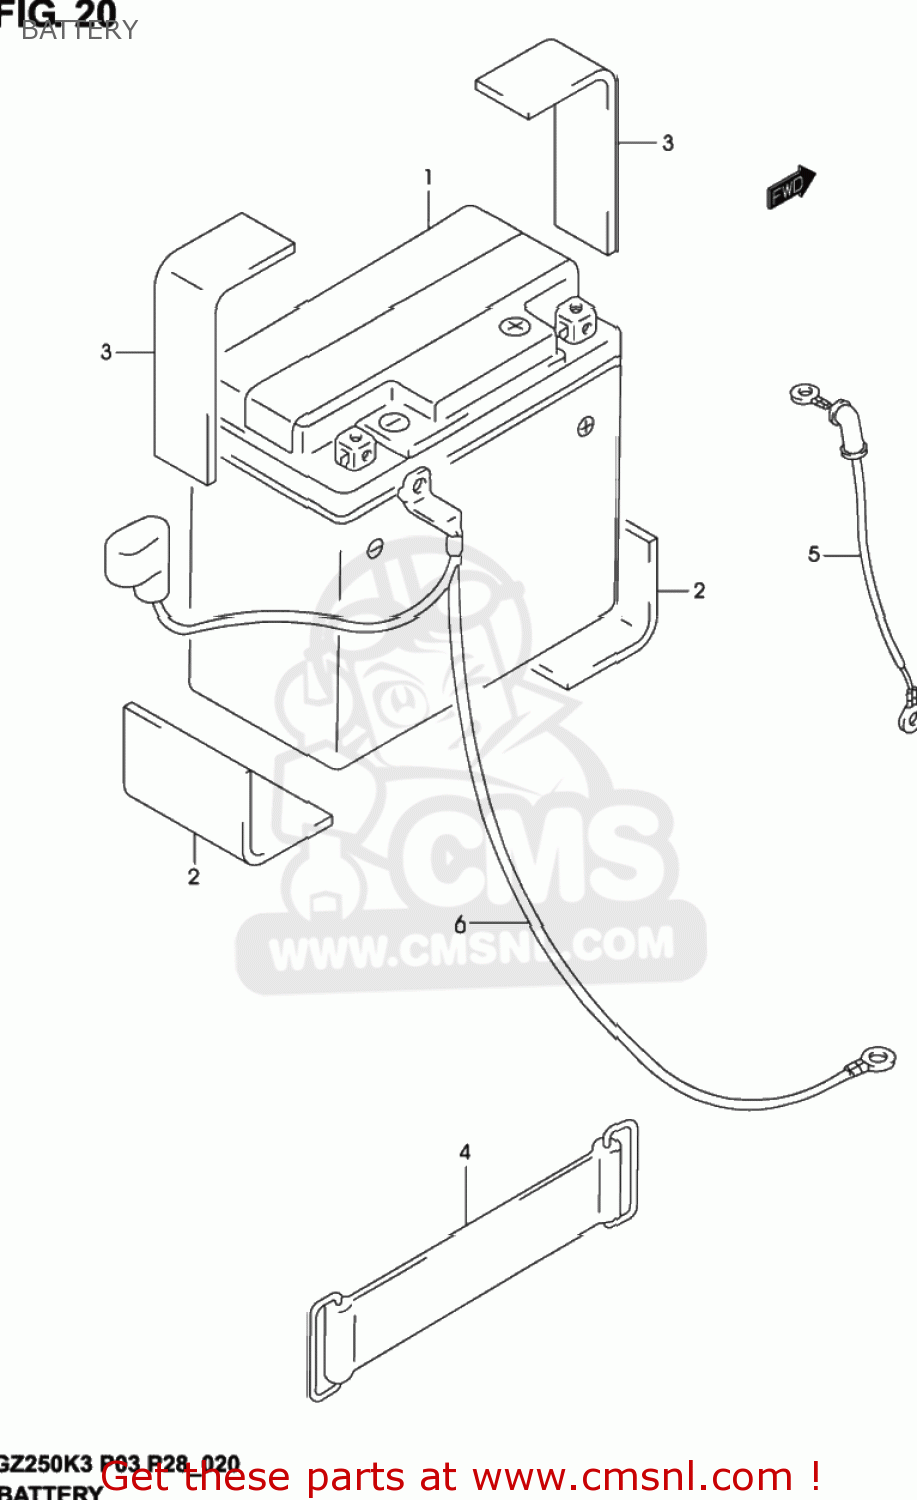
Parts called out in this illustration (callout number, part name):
1	BATTERY ASSEMBLY (12V) FTX
2	PROTECTOR,BATTERY
3	PROTECTOR,20X9
4	BAND
5	WIRE,BATTERY PLUS LEAD
6	WIRE,BATTERY MINUS
